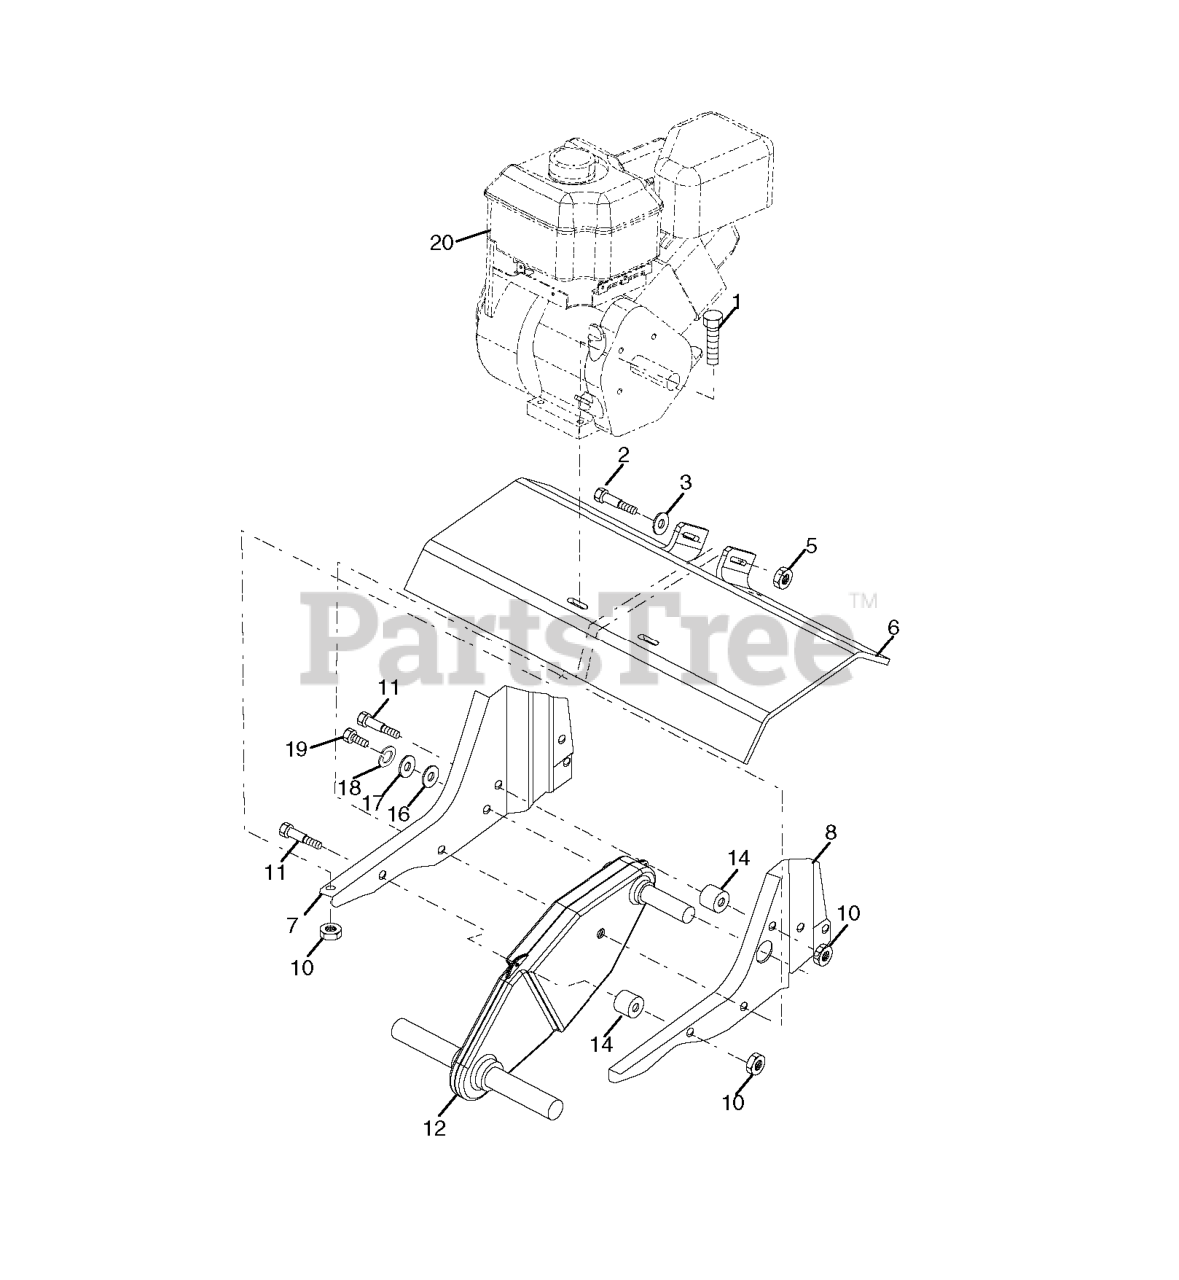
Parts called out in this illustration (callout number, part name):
1	BOLT
2	Bolt, Hex 3/8-16 x 3-1/4
3	WASHER
5	NUT LOCK FLG 3/8-16 UNC
6	SHIELD.PNT.TINE.24".ORANGE
7	RP.BRACKET.ENGINE.RH.TILLER.BL
8	BRACKET.ENGINE.TILLER.LH.BLACK
10	LOCKNUT-FLANGE 5/16-18
11	BOLT, HEX HEAD 5/16-18 X 2.5
12	TRANSMISSION.ASM.W/1".D-SHAFT
16	REPL BY 819 09 14-16
18	LOCKWASHER
19	Bolt, Hex 1/4-28 x 3/4 Gr. 5
